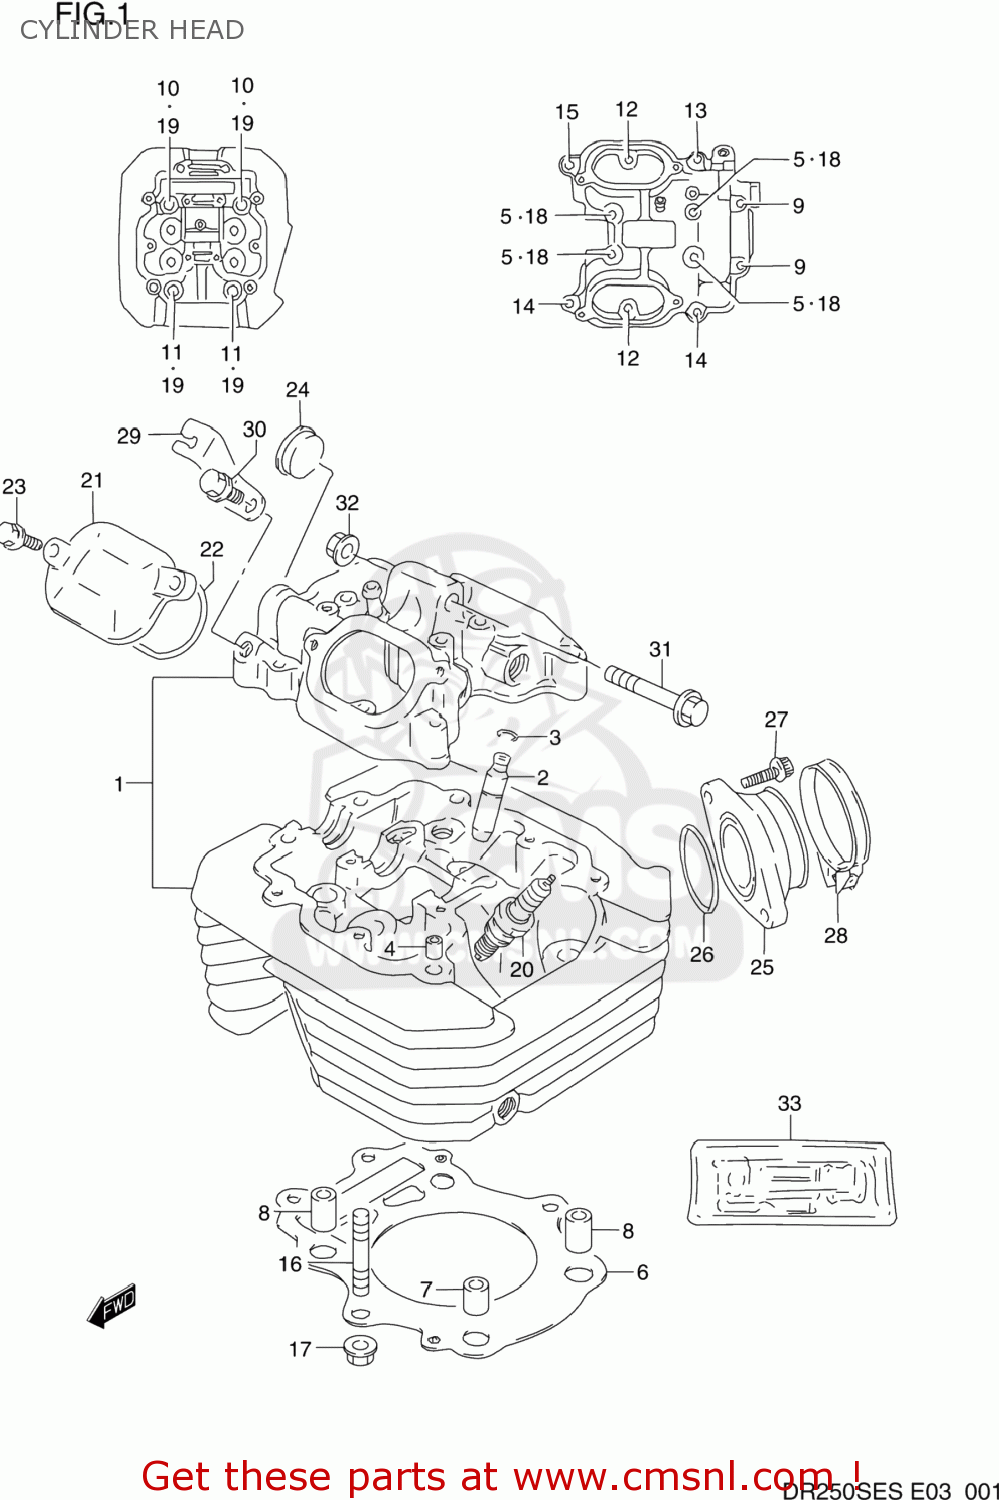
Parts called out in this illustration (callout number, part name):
1	HEAD ASSEMBLY,CYLINDER
2	GUIDE,VALVE
3	RING,SNAP
4	PIN(6.2X8X11)
5	BOLT(6X55)
6	GASKET,CYLINDER HEAD (NAS)
7	PIN
8	PIN(10.4X13X22)
9	BOLT(6X115)
10	BOLT(10X180)
11	BOLT(10X155)
12	BOLT
13	BOLT
14	BOLT(6X35)
15	BOLT(6X39)
16	BOLT,STUD
17	NUT
18	GASKET(5.8X13X1.2) (NAS)
19	WASHER (10.5X22X2.3)
20	PLUG,SPARK(DPR9EA-9)
21	CAP,INSPECTION
22	GASKET (NAS)
23	BOLT
24	PLUG,OD:30
25	PIPE ASSY,INTAKE
26	O RING(D:2.4,ID:39.7)
27	BOLT
28	CLAMP
29	LEVER,DECOMP SHAFT RH
30	BOLT, LOWER
31	BOLT(8X65)
32	NUT
33	GASKET (NAS)
